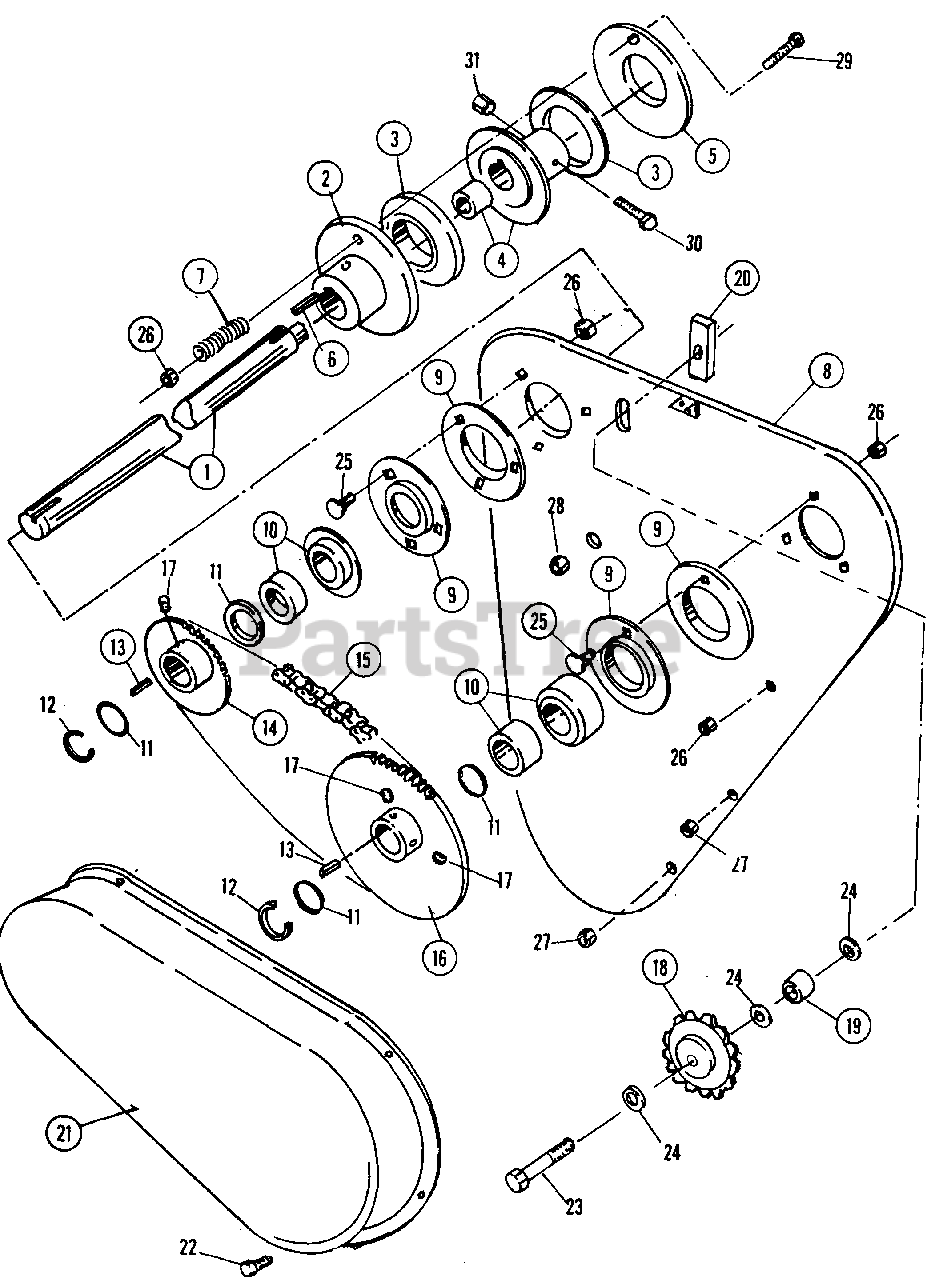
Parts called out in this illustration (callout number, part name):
1	SHAFT, DRIVE
2	PLATE, HUB END
3	DISC, CLUTCH
4	HUB & BEARING ASSEMBLY
5	PRESSURE - PLATE
6	KEY, 1/4 SQUARE X 1-1/2
7	SPRING, PRESSURE
8	COVER, INNER
9	FLANGETTE, 3-HOLE
10	BEARING, SEALED
11	WASHER, 1" I.D. SHIM
12	RING, RETAINING .915 x .044
13	KEY, 1/4 SQUARE x 1"
14	SPROCKET, 50P, 16 TOOTH
15	CHAIN, ASA 50 ROLLER 78 Pitches
16	SPROCKET, 40 TOOTH
17	SETSCREW, HEX SOCKET
18	SPROCKET, IDLER
19	SPACER, IDLER SPROCKET
20	STRAP, IDLER SUPPORT
21	SHIELD, OUTER DRIVE COVER
22	SCREW, 5/16-18 x 5/8 SELF-TAPPING
23	BOLT, 1/2-13 x 2-3/4 HEX - GRADE 5
24	NUT, 1/2" PLAIN
25	BOLT, 5/16-18 x 3/4 CARRIAGE
26	LOCKNUT, 5/16-18 HEX
27	LOCKNUT, 3/8-16 HEX
28	LOCKNUT, 1/2-13 HEX
29	BOLT, 5/16-18 x 2-1/2 HEX - GRADE 5
30	BOLT, 1/4-20 x 2-1/2 HEX - GRADE 2
31	LOCKNUT, 1/4-20 HEX
